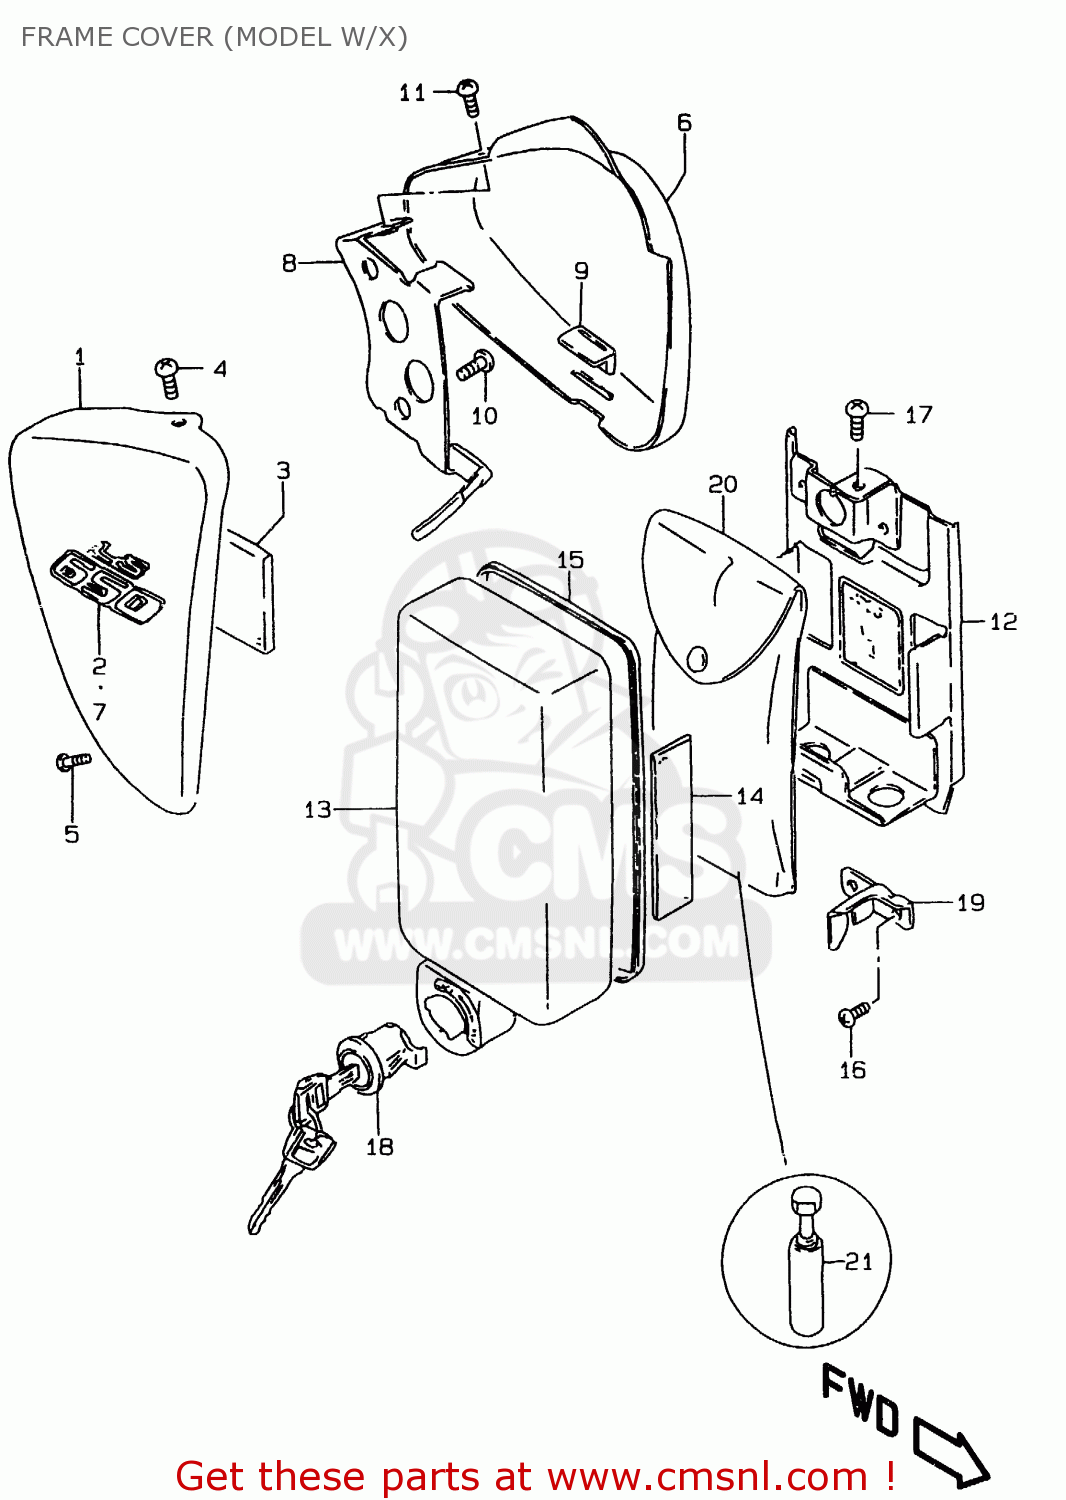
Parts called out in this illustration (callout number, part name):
1	COVER ASSY,FRAME,R(BLACK)
2	EMBLEM,FRAME COVER
3	PAD
4	SCREW
5	SCREW
6	COVER ASSEMBLY,FRAME,LEFT
7	EMBLEM,FRAME COVER
8	BRACKET,FRAME COVER,L
9	CUSHION,FRAME COVER
10	SCREW
11	SCREW
12	HOLDER,TOOL
13	COVER COMP,TOOL HOLDER
14	PROTECTOR(80X80X2)
15	MOLDING
16	SCREW
17	SCREW
18	LOCK SET,TOOL HOLDER
19	PLATE,TOOL HOLDER LOCK
20	TOOL ASSY
21	GAUGE ASSY,TENSION
